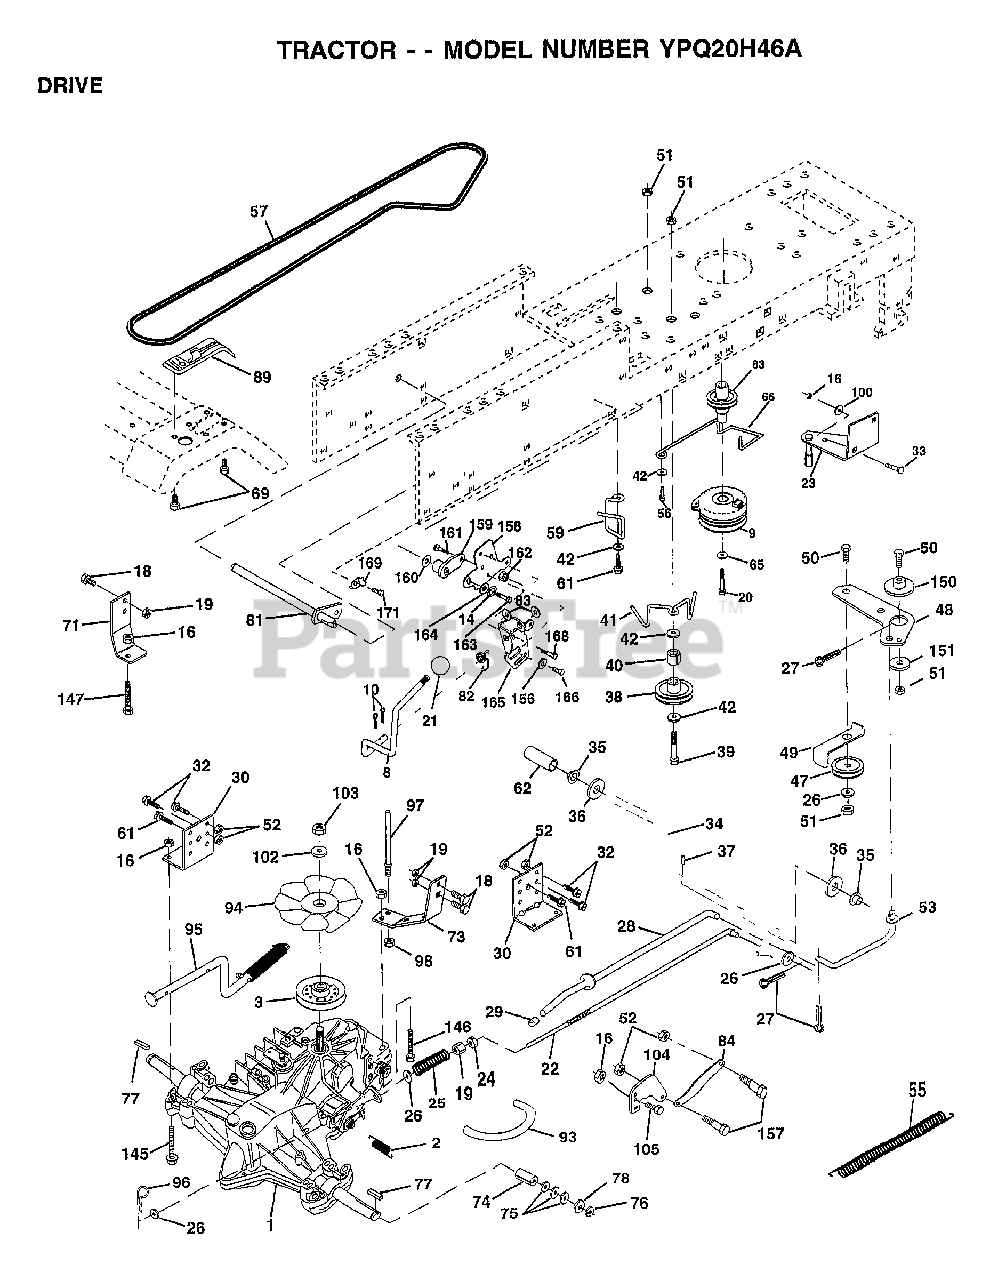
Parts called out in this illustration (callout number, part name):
2	SPRING RET BRAKE
3	PULLEY.TRANSAXLE
8	ROD.SHIFT.FEND.ADJ.YT
9	CLUTCH.ELECTRIC
10	PIN COTTER 1/8
14	LOCKWASHER
16	NUT
18	BOLT
19	NUT
21	KNOB.DUCKHEAD.1/2
22	ROD.BRAKE.HYDRO.
23	BRACKET.CLUT.MTG.
24	NUT
25	SPRING ROD LT
26	WASHER
27	COTTER PIN
28	ROD.BRAKE.PARK.LT
29	PLUNGER CAP T
30	TRANSAXLE MTG BKT
32	BOLT
33	BOLT
34	SHAFT ASM-PEDAL F
35	NYLON BEARING
36	WASHER LT
38	FLAT IDLER PULLEY
39	BOLT
40	SPACER T
41	"KEEPER,BELT.IDLER FLAT"
42	WASHER
48	BELLCRANK.CLUTCH
49	RETAIN BELT
53	"LINK, CLUTCH T"
55	"SPRING, RETURN LT"
57	"BELT.GD DRV 82"""
59	KEEPER BELT CNTSP
61	SCREW
62	PEDAL COVER T
63	PULLEY.CLUTCH.EVX
65	LOCKWASHER
66	KEEPER-BELT
69	SCREW HEXWSH H-L
71	STRAP TORQ LH HYD
73	"STRAP-TORQUE,RH"
74	SPACER SPLIT
75	WASHER
76	E-RING LT
77	SQUARE KEY
78	WASHER
81	SHAFT.ASM.CROSS
82	"SPRING,TORSION"
83	WASHER
84	LINK.TRANSAXLE.LT/YT
89	CONSOLE.SHIFT.AUTO.YT/GT.BLACK
93	"LINE FUEL HYD 4"""
94	"FAN 7"" HYDRO"
95	CONTROL.ASM.BYPASS.HYDRO.99
96	RETAINER M
97	BOLT KEEPER RH
98	NUT
100	WASHER M
102	WASHER BELLEVILLE
104	ARM CONTROL HYDRO
105	SCREW CAP 5/16-18
145	BOLT.HEX.FLGHD
146	BOLT.HEX.FLGHD.
147	BOLT.HEX.FLGHD
150	BUSHING.BELLCRANK.GRD.DR
151	WASHER
156	WASHER.SRRTD.5/16
157	"BOLT,SHOULDER"
158	BRKT.SHIFT.MOUNT
159	HUB.SHIFT
160	WASHER
161	BOLT T
164	WASHER.5/8X.281X10GA
165	BRKT.PIVOT.LEVER
166	SCREW.5/16-18X5/8
168	BOLT.SHOULDER.5/16-18X.561
169	PLATE.FASTENING
171	SCREW LT
